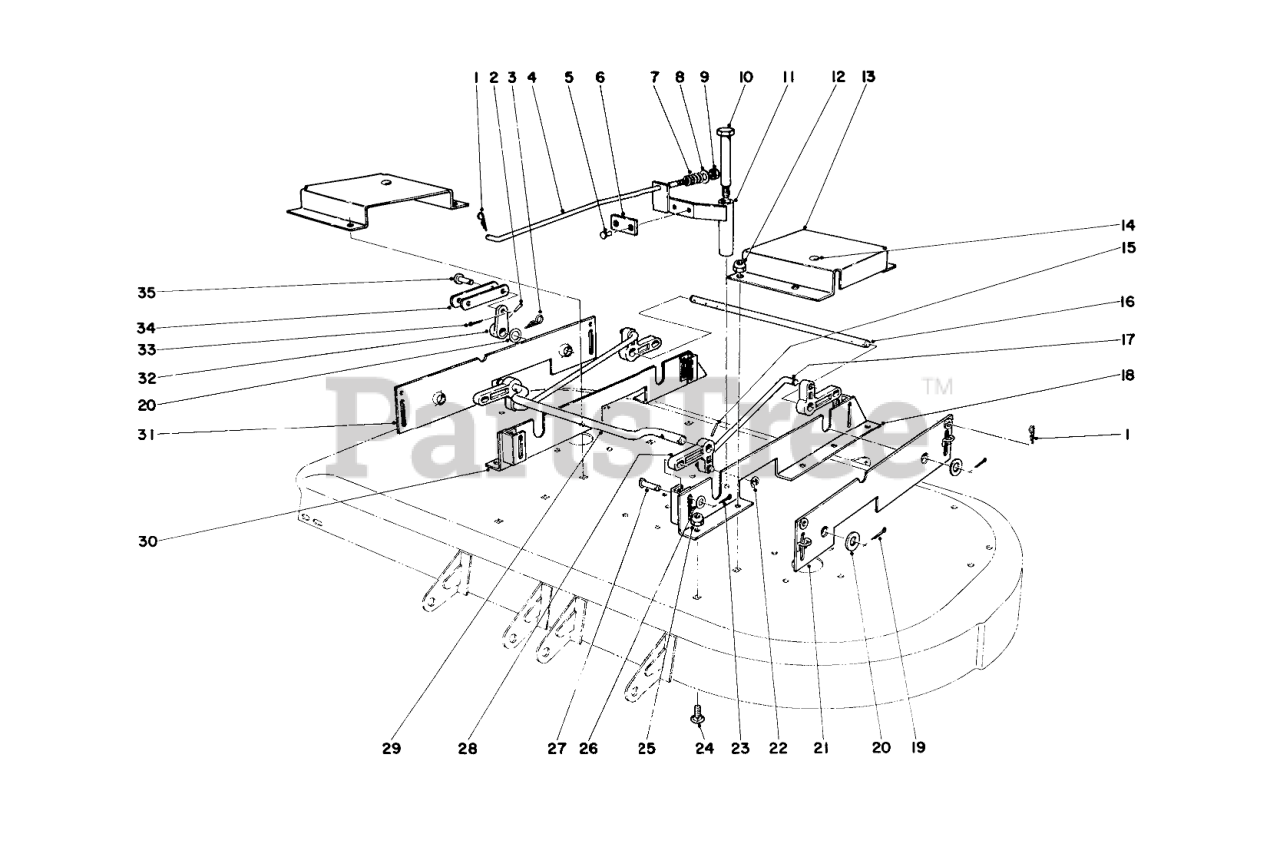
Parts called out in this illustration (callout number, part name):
1	PIN-COTTER, HAIR
2	Pin Drive
3	HAIRPIN COTTER
4	Brake Rod
6	BLADE BRAKE LINING
7	Spring
8	Washer
9	NUT-LOCK, CONE
10	Shoulder Bolt
11	a. Bracket
12	NUT-LOCK, CONE
13	Cover
14	Plug Button
15	PIN-SPRING
16	Rear Pivot Shaft
17	Lift Link
18	Bracket Assy. Lower
19	PIN-COTTER
20	Washer
21	Mower Plate Housing
22	RING-RETAINING, EXT
23	PIN-COTTER
24	Screw
25	NUT-LOCK, CONE
26	Washer
27	Lift Pin
28	Bell Crank
29	Front Pivot Shaft
30	Bracket Assy. Lower
31	Mower Plate Housing
32	Lever
33	PIN-COTTER
34	Adjusting Link
35	Pin
